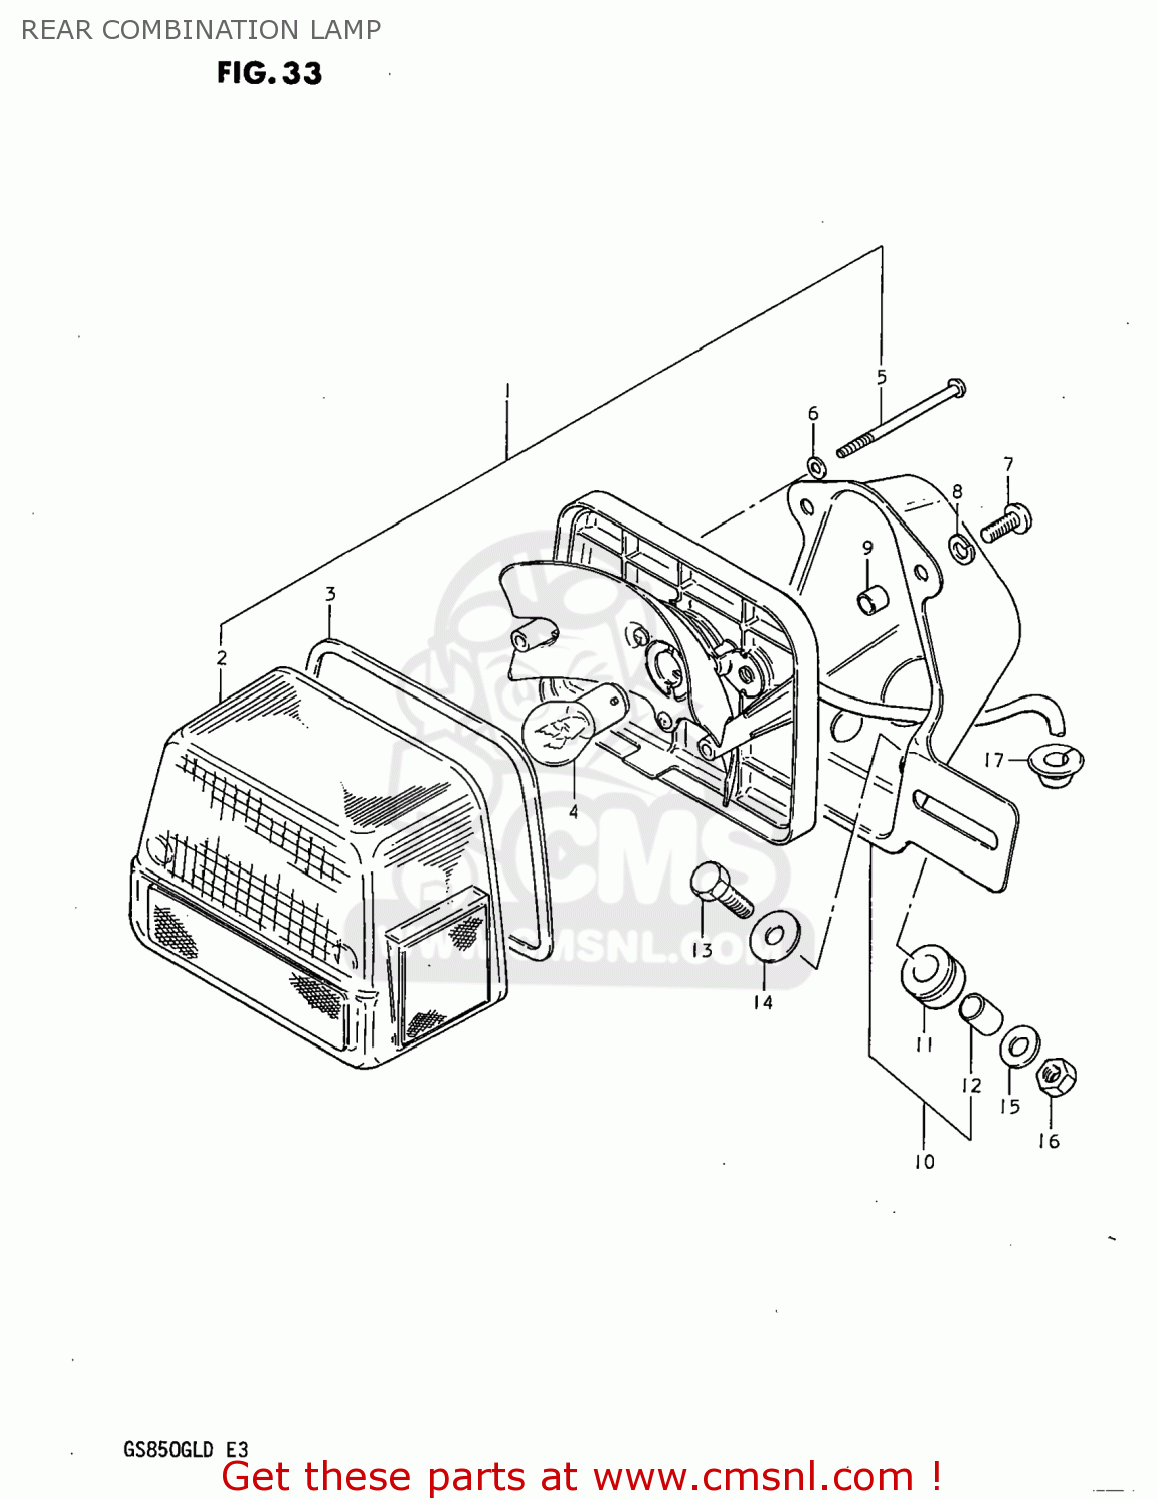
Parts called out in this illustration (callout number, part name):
1	LAMP UNIT,RR COMBNATION
2	LENS
3	GASKET (NAS)
4	BULB(12V23W)
5	SCREW
6	GASKET (NAS)
7	SCREW
8	LOCK WASHER
9	SPACER
10	BRACKET UNIT,TAIL LAMP
11	CUSHION
12	SPACER
13	BOLT
14	WASHER (6.5X20X1.2)
15	WASHER
16	NUT
17	GROMMET
